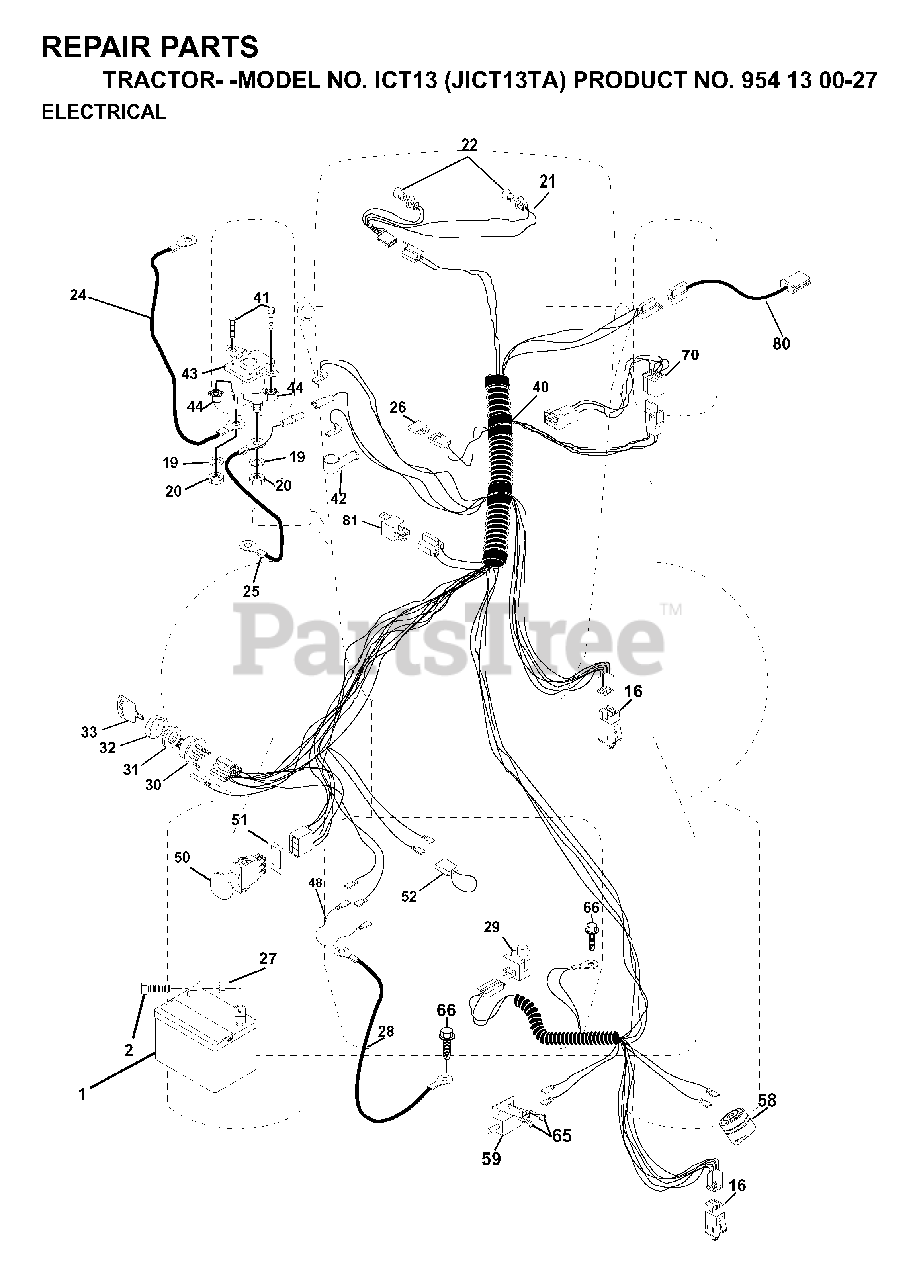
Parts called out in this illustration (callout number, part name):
1	BATTERY 12 VOLT 25 AMP
16	SWITCH INTERLOCK
19	LOCKWASHER
20	NUT
21	HARNESS ASM, LIGHT W/4152J
22	LIGHTBULB
24	CABLE ASM
25	CABLE BATTERY
26	FUSE 15 AMP
27	NUT
28	CABLE GROUND
29	PLUNGER SWITCH (COLOR:OLIVE)
30	SWITCH.IGNITION.4.POSITION
31	NUT IGNITION
32	COVER SWITCH KEY
42	TERMINAL COVER
43	SOLINOID
51	RETAINING RING
52	WIRE PROTECTION LOOP
70	HARNES.ENG.TEC/KOHL
80	HARNESS, CLUTCH
81	RELAY.ASSY.T
